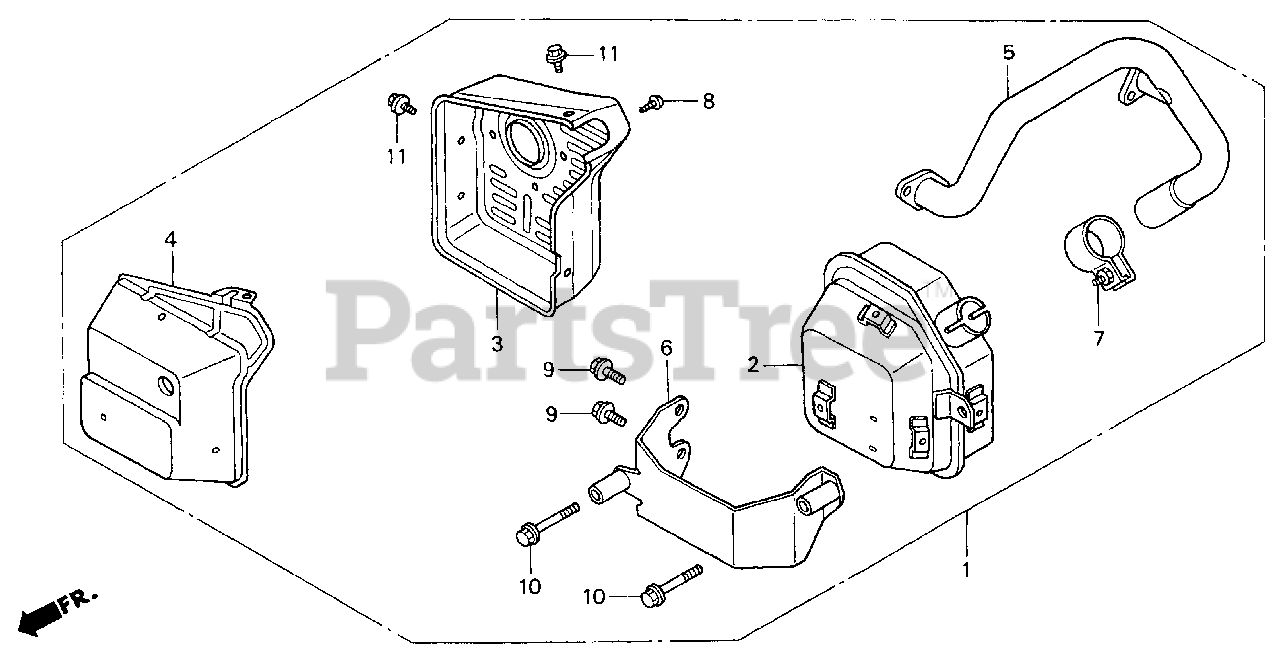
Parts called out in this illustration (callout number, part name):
1	MUFFLER KIT (SIDE-L) (N/A: SEE COMPONENTS)
2	MUFFLER (SIDE-L)
3	PROTECTOR, MUFFLER (SIDE-L)
4	PROTECTOR, RR. MUFFLER (SIDE-L)
5	PIPE, EX. (SIDE-L)
6	STAY, MUFFLER (SIDE-L)
7	BAND ASSY.
8	SCREW, PAN (6X8)
9	BOLT, FLANGE (6X8)
10	BOLT, FLANGE (8X14)
11	BOLT, FLANGE (8X55)
